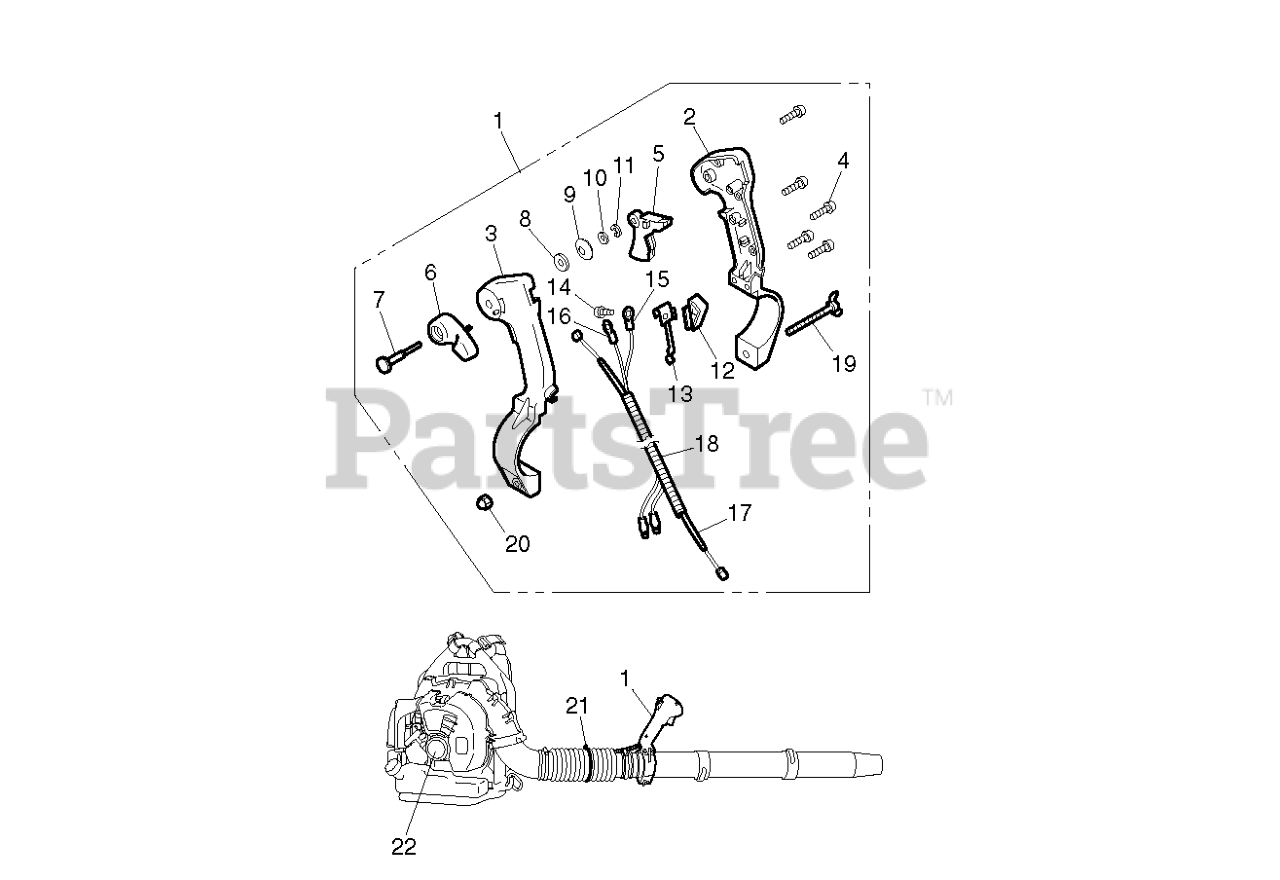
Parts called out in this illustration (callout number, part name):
1	LEVER
3	CASE
4	SCREW 4X14(T)
5	LEVER THROTTLE
6	RP_LEVER (RPLS T402325430)
7	SHAFT
8	WASHER(T)
9	RP_SPRING WASHER
10	WASHER
11	RP_CLIP(T)
12	SWTICH (T)
13	SPRING (RPLS T402325720)
14	RP_SCREW 4X10(T)
16	CORD(T)
19	BOLT WING
22	LABEL RECOIL 848L3W90C0
